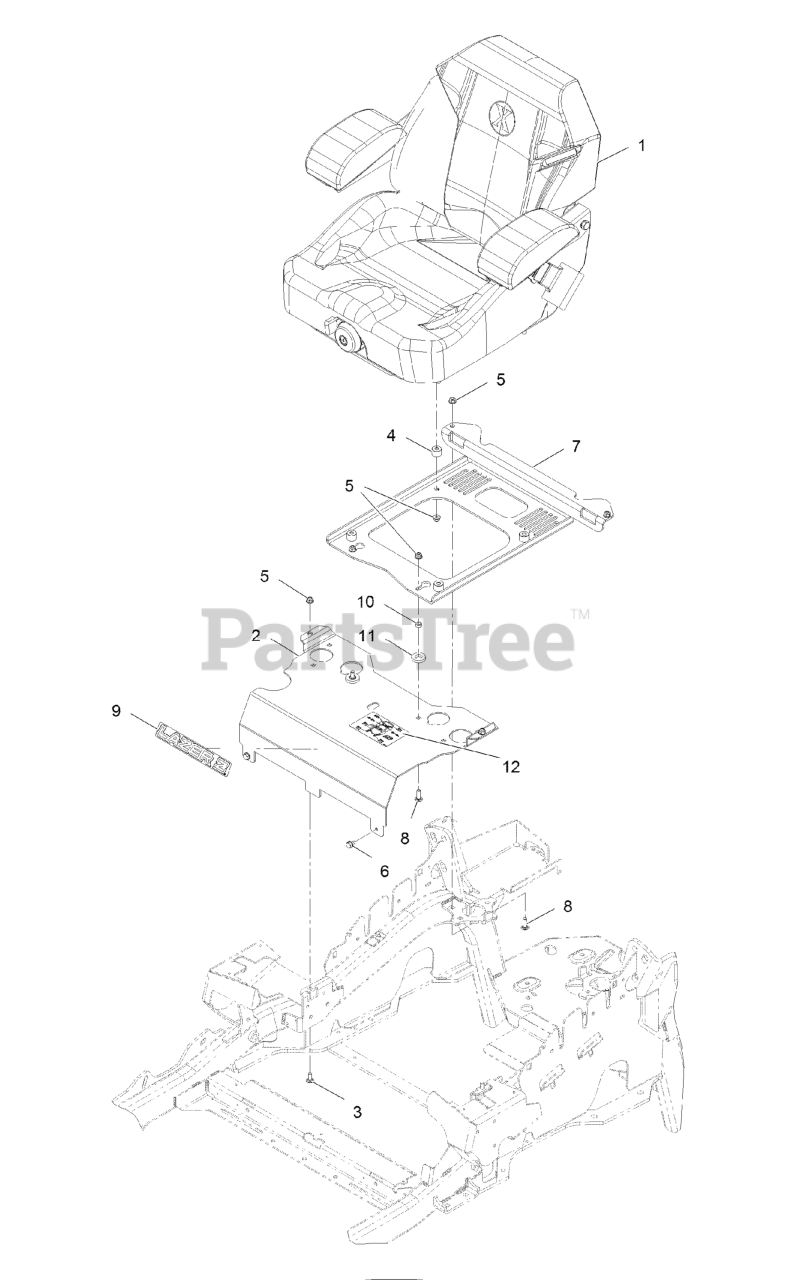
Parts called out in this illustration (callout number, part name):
1	ASM-SEAT LZE
2	Panel-Front, Seat Mount
3	SCREW-CARR
4	NUT-HF, NI
6	PLATE-SUPPORT, SEAT
7	SCREW-CARR
8	DECAL, LAZER MODEL
9	NUT-HEX
11	DECAL-SERVICE AID
